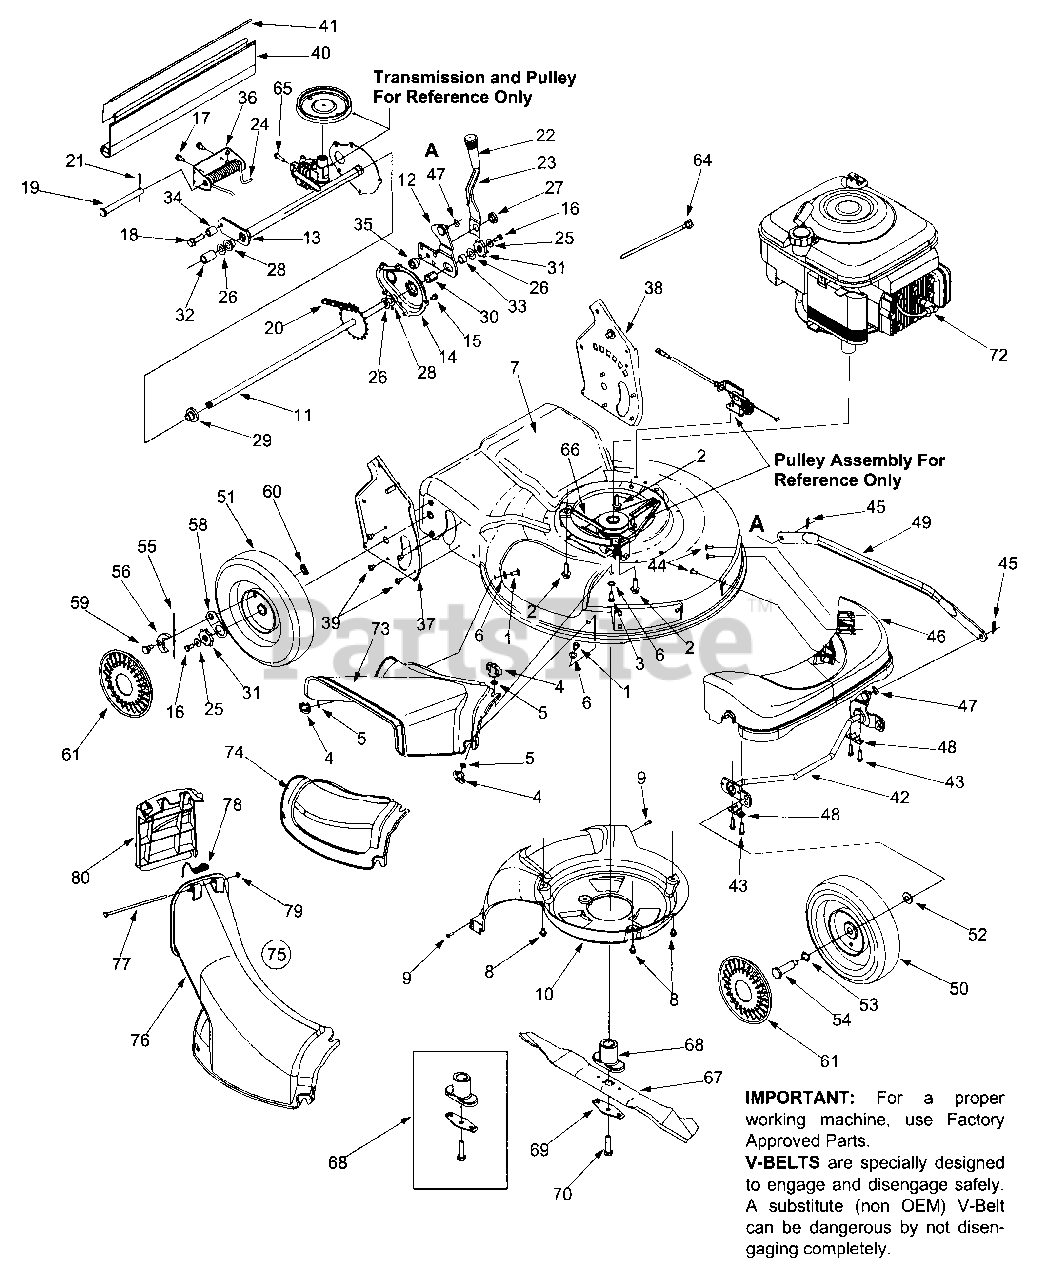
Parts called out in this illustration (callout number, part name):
1	Carriage screw 1/4-20 x .62
2	TT Screw 3/8-18:1.00
3	Screw 1/4-20 x .750
4	Wing Nut 1/4-20
5	Push Nut .25 I.D. x .50 O.D.
6	Flat Washer .334 I.D.x.62 x.03
8	TT Screw 1/4-20 x .375
9	HL Screw 1/2-14 x .750
10	Baffle
11	Rear Axle Ass'y
16	Cap Screw HH 1/4-20 x .620
17	AB Scr. 1/4-14 x .625
18	Scr. 3/8 116 x .25
19	Clevis Pin .50 Dia.x4.82
20	Chain-Endls. #48 .500P x 24
21	Cotter Pin .1250.D. x .75
24	Torsion Spring
25	Bell Wash. .285 x .75 x .082
26	Fl. Wash .508 I.D. 1.000 x.020
27	Nut Shld. .825 Dia. x .165
28	Hx.Flg. Brg .506 I.D. x .590
29	Hx.Flg. Brg .506 LD. x .715
30	Hx. Slv. Brg .504 I.D. x .830
31	Wheel Rachet
32	Spacer .550 I.D. x /750 O.D.
33	Spacer .51 I.D. x .70 O.D. x 38
34	Spacer .385 x .624 x .700
35	Shld. Spacer .385 I.D. X .715
40	Trail Shield
41	Trail Shield Wire
43	Hx Scr. Wash Hd. Hi.-Lo.
44	Scr. Torx, Truss Hi.-Lo.
45	Cotter Pin .072 x 1.12 Lg.
46	Front Axle Cover, Grey
47	Bowed Washer
48	Bush. Block .505 Dia. x .62
50	Wheel 8 x 2
51	Wheel 9 x 2
52	Spr. Wash. .401 x .870 x .063
53	Wave Wash .510 x .750 x .017
54	Shldr Scr .498 x 1.445 x 3/8-16
55	Spring, Ratchet, Plastic
56	Pawl: LH.
58	Ratchet Pawl Plate
59	Shoulder Scr. .340 x .285
60	Top Lock Tab Weld Nut 1/4-20
61	Hubcap: Rad. Spoke Grey
65	Hex Screw 5/16-18
66	V-Belt
67	21" Mulching Blade
68	Blade Adapter Kit
69	Blade Bell Suport
70	Hex Bolt 3/8-24 x 2.5" Lg.
72	Spark Plug Insulator
73	Side Discharge Chute
74	Mulch Cover
75	Rear Chute Ass'y w/ Door
76	Discharge Chute
78	Torsion Spring
80	Chute Door
